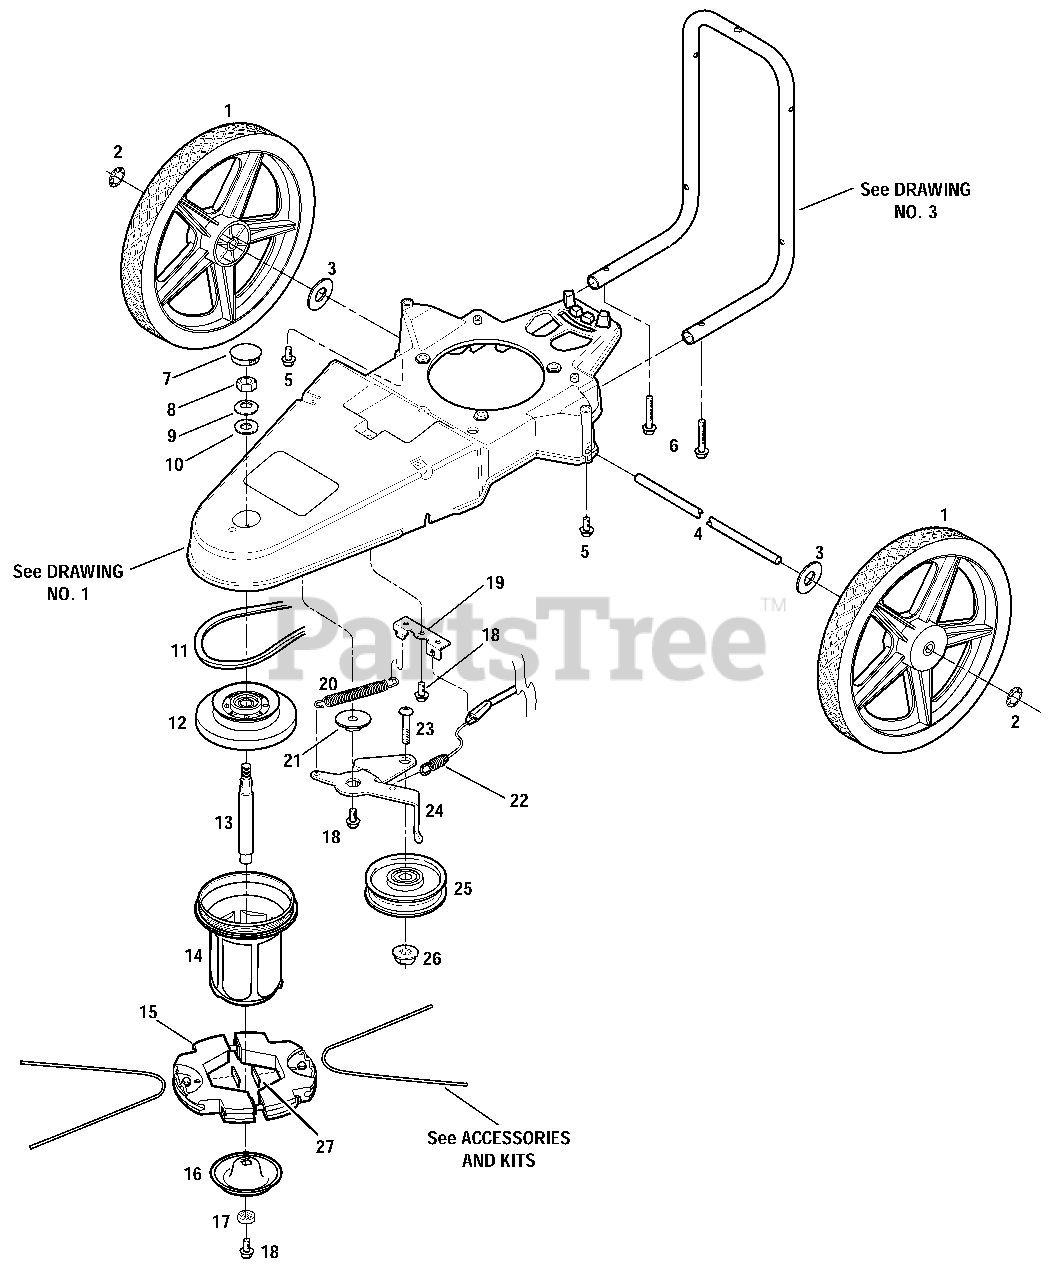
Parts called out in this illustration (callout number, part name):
1	Wheel/Tire Assembly
2	Locking Retaining Ring
3	Flat Washer
5	Self-Tap Screw, 5/16-18 x 3/4
6	Self-Tap Screw, 5/16-18 x 2
7	Cap Plug
8	Hex Lock Nut, 1/2-13
9	Belleville Washer
10	Hardened Washer
12	Spindle Head Adapter
13	Spindle Shaft
14	Spindle Head Assembly
15	Trimmer Head Assembly
16	Wear Cup
17	Square Washer
18	Self-Tap Screw, 5/16-18 x 3/4
19	Cable Bracket
20	Idler Spring
21	Flat Washer
22	Control Cable - Trimmer Head
23	Button Hd. Screw, 3/8-16 x 1-1/2
24	Idler Arm
25	Idler Pulley
26	Flange Lock Nut, 3/8-16
27	Rubber Shim Kit
